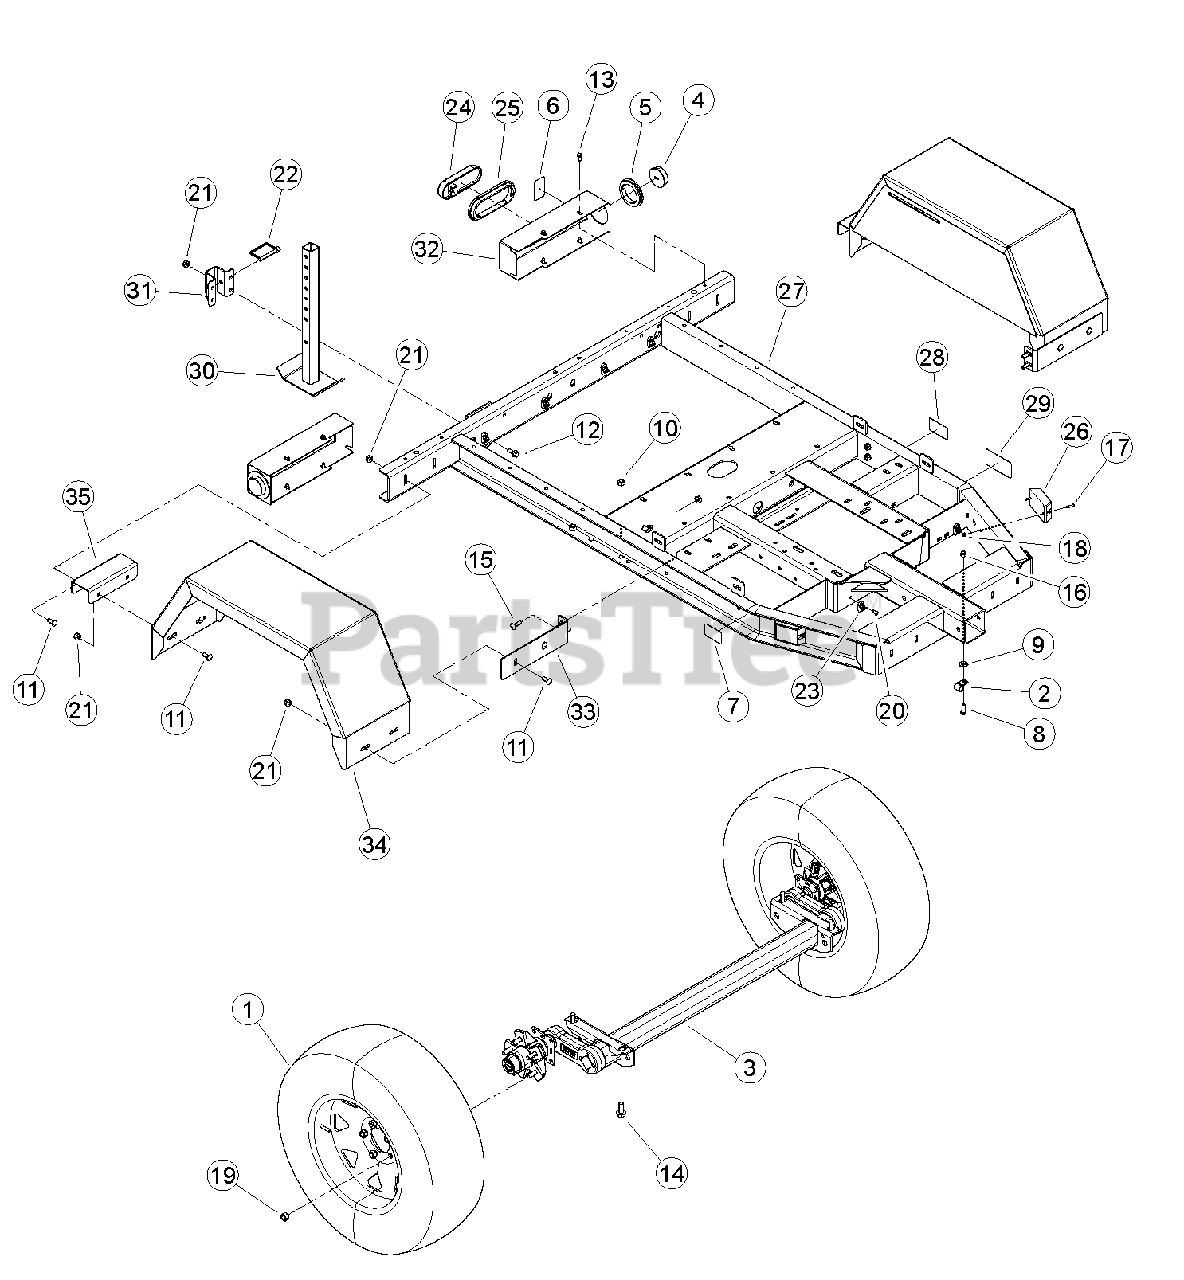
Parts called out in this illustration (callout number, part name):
1	ASSEMBLY, 15 INCH TIRE + WHEEL
2	CLAMP, 9/16 COATED
3	AXLE, 2500 LB TORSION
4	LIGHT, RED CLEARANCE
5	GROMMET, CLEARANCE LIGHT
6	REFLECTOR, WIDE ANGLE RED
7	REFLECTOR, WIDE ANGLE AMBER
8	BOLT, 3/8 X 1 HEX HD GR5 ZP
9	WASHER, 3/8" FLAT ZP
10	NUT, 1/2" CENTERLOCK GRB ZP
11	BOLT, 3/8 X 1" GR5 CRG NC ZP
12	BOLT, 3/8 X 1 FLANGE NC
13	SCREW, 11/32 X 7/8 HWH AB THREAD ZP
14	BOLT, 1/2 -13 X 1-1/4 FLANGE NC
15	BOLT, 3/8 X 1-1/4" GR5 CRG NC ZP
16	NUT, 3/8" NE NYLOCK ZP
17	SCREW, MCH 10-24 X 1" RND HD PHL ZP
18	NUT, 10/24 NYLOCK TYPE NM ZP
19	NUT, 1/2-20 WHEEL
20	RIVET, AL BLIND 1/4 X 3/4 DOME HEAD
21	NUT, 3/8-16 NYLOCK FLANGE
22	PIN, 3/8 X 2-3/4" SNAP
23	CLAMP, CABLE MOUNT
24	TAIL LIGHT, OVAL LED
25	GROMMET, OVAL TAIL LIGHT
26	LIGHT, AMBER MARKER
27	ASSEMBLY, CH611DH TRAILER/DECALS
28	DECAL, P215/70R15 100 LB LOAD RATING
29	DECAL, EPA EMISSION
30	WELDMENT, REAR STABILIZER
31	GUIDE, TRAILER SUPPORT
32	BRACKET, TAILLIGHT
33	BRACKET, FENDER
34	WELDMENT, CHIPPER FENDER
35	PLATE, FENDER SPACER
